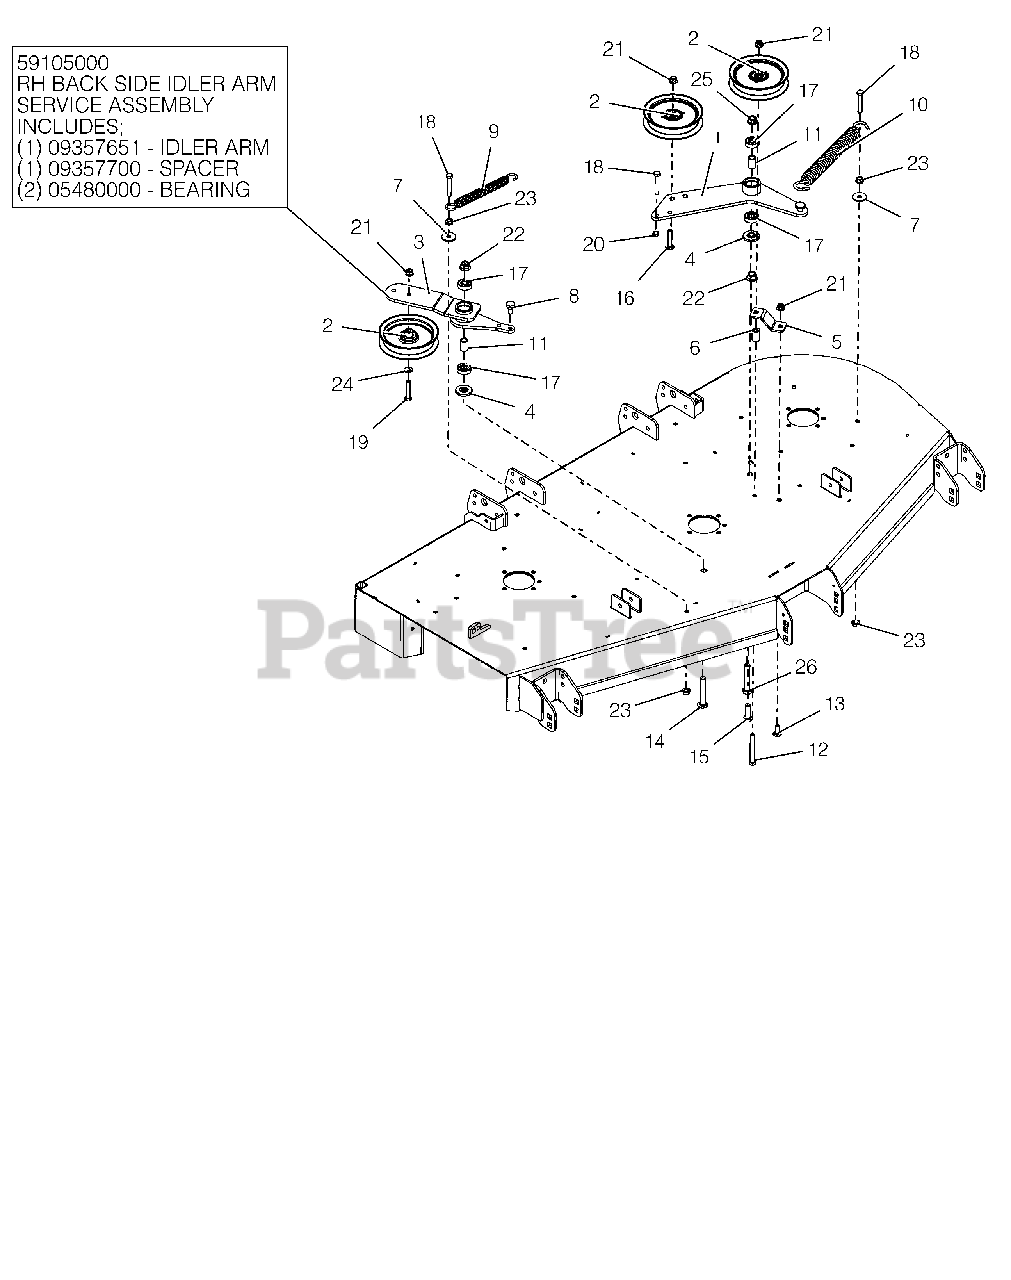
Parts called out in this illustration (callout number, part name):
1	DECK PTO IDLER ARM WLDMT - BLK
2	IDLER, FLAT 5.00"
3	DECK RH IDLER ARM WMT - BLK
3	RH BACKSIDE IDLER ARM ASSEMBLY
3	SPACER .510 X .75 X 1.1485
3	BRG-BALL .50X1.38X.438 SEALED
4	SPACER, IDLER ARM
5	PTO FIXED IDLER MTG BRKT -RED
6	BUSHING, SLV .380X.750X1.190
7	WSHR-FL-STL .406X1.375X.135 YZ
8	BLT,SHLDR EP .38-16X.30 HEX YZ
9	SPRING, EXTENSION
10	SPRING, EXTENSION
11	SPACER .510 X .75 X 1.1485
12	@BLT-HEX .38-16X3.25 GR5 YWZC
13	@BLT-RDHDSHSQNK.38-16X1.0 G5YZ
14	BLT,RDHDSQSHNK.50-13X3.25 G5YZ
15	@BLT-HEX .50-13X1.50 GR5 YWZC
16	BLT-RDHDSQNK .38-16X2.00 SHTYW
17	BRG-BALL .500X1.38X.437
18	@BLT-HEX .38-16X2.25 GR5 YWZC
19	@BLT-HEX .38-16X2.00 GR5 YWZC
20	NUT-HEX-JAM .375-16 YWZC
21	@NUT-LK-NYL-FLG .38-16 YWZC
22	@NUT-LK-NYL-FLG .50-13 YWZC
23	@NUT-SPNLK-FLG .375-16 YWZC
24	@WSHR-FL-STL.406X.812X.065 YWZ
25	NUT-LK-CTR-FLG .50-13 YWZC
26	@BLT-HEX .50-13X3.00 GR5 YWZC
